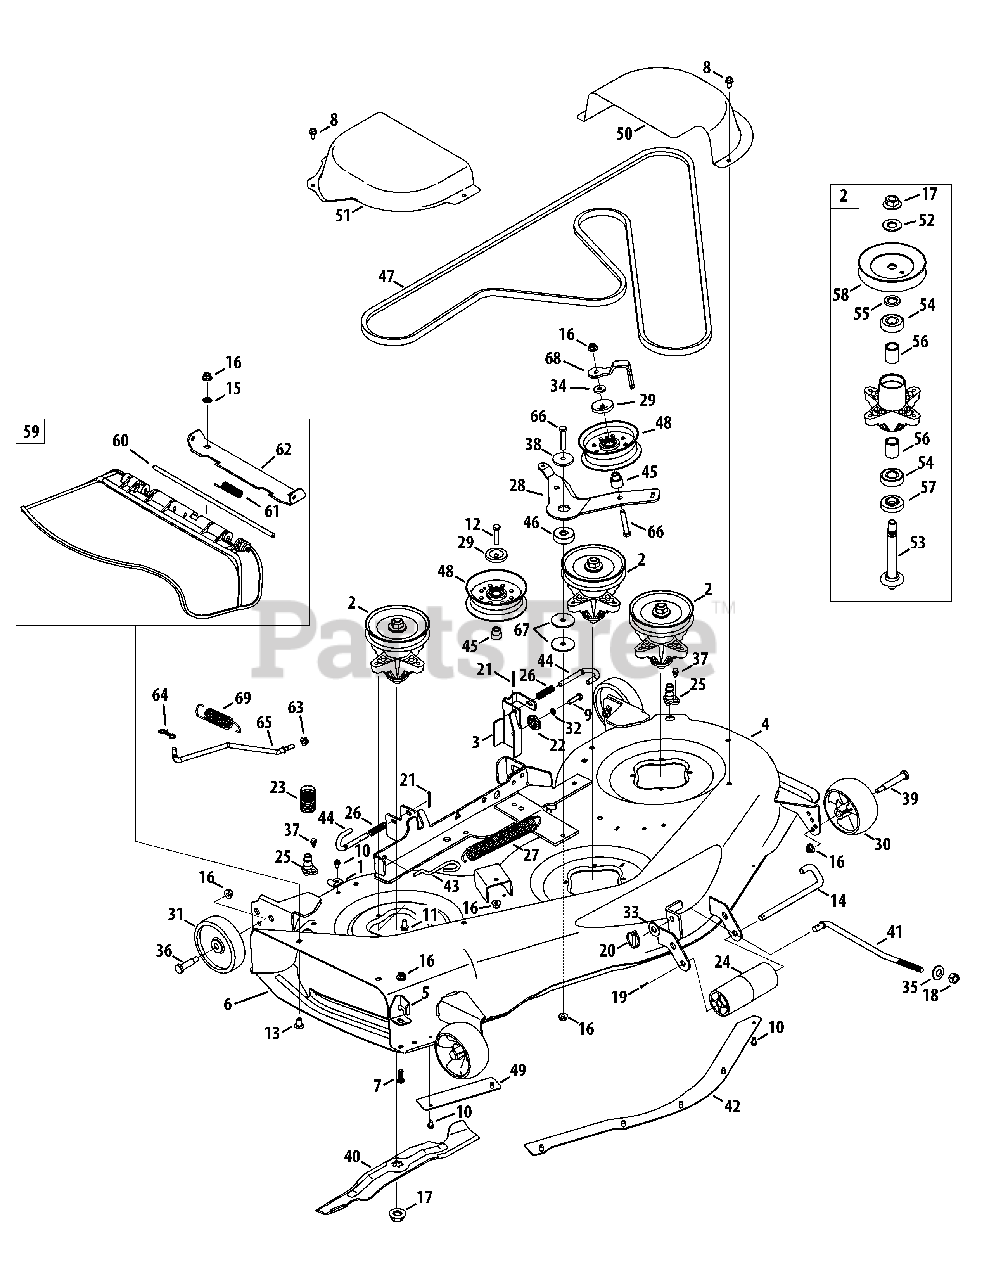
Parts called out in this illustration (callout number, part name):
1	Bracket, Hook, Retainer
2	Spindle Assembly, Pulley, 5.39 Dia.
3	Bracket Assembly, Deck, Hanger LH
7	Hex Screw, 3/8-16, 1.00, Gr5, Spec
8	Screw, Self-tapping, 5/16-18, .750,
9	Hex Screw, 5/16-18, 1.25, Gr5, Std
10	Screw, Self-tapping, 1/4-20, 0.500
11	Screw, Self-tapping, 5/16-18, 0.750,
12	Hex Screw, 3/8-16, 2.00, Gr5, Std
13	Bolt, Carriage, 3/8-16, 0.75, Gr1
14	Roller Pin-1/2 Dia. x 7.31
15	Nut, Push, 3/8
16	Nut, Flange Lock, 3/8-16, Nylon
17	Nut, Flange, 5/8-18
18	Nut, 1/2-13
19	Pin, Cotter, 3/32, 1.0
20	Pin, Lynch, .1875
21	Pin, Cotter, 1/8 x 1.25
22	Gear, Deck, Adjustment
23	Coupler, Water
24	Roller, Front
25	Deck Wash Nozzle
26	Spring, Compression, .535 OD x 1.751
27	Spring, Extension, 1.25 OD x 8.5
28	Pivot Idler bracket
29	Pulley Cap
30	Wheel, Deck, 5.0 Dia. Ball
31	Wheel, Deck 5.0 x 1.38
32	Washer, Lock, 5/16, Regular Duty
33	Washer, Flat, .531 x 1.25 x .100
34	Flat Washer, .385 x 1.00 x .135
35	Washer, Bell, .63 x 1.25 x .18
36	Bolt, Shoulder, .496 x 1.525, 3/8-16
37	Shoulder Screw, 1/4-20 x 0.50
38	Shoulder Spacer, .970 x .190
39	Bolt, Shoulder, .496 x 2.50, 3/8-16
40	Blade, 17.90 Star 2 In 1
41	Rod, Lift, Deck, Front, 11.7
42	Skirt, Center, 50"
43	Rod, Deck Spring Hook
44	Rod, Deck Release
45	Shoulder Spacer
46	Spacer, .385 ID x 1.75 OD x .585
47	Belt, V-Type
48	Pulley, Idler, 4.50" Dia.
49	Skirt, RH, 50"
50	Cover, Belt, LH 50"
51	Cover, Belt, RH 50"
52	Flat Washer, .760 x 1.50 x .120
53	Shaft, Spindle, 5.75
54	Bearing, Ball, .787id x 1.85 Od x .551
55	Spacer, .79 ID x 1.25 OD x .175
56	Spacer, .80 x 1.10 x 1.322
57	Spacer, .79 x 1.82 x .55
58	Pulley, Deck, 5.39 Dia.
59	Chute Assembly
60	Pin, Hinge, .3175 Dia. x 14.06 ,1
61	Spring, Torsion, .44 I.D. x 2.0,
62	Bracket, Chute 50/54"
63	Nut, Flange Lock, 5/16-18, Nylon
64	Pin, Cotter, Bow-Tie
65	Rod, Support, Deck (Tuff Torq)
66	Hex Screw, 3/8-16, 2.25, Gr5, Std
67	Flat Washer, .380 x 2.00 x .120
68	Idler Keeper
69	Spring, Extension, 1.15 OD x 5.99
